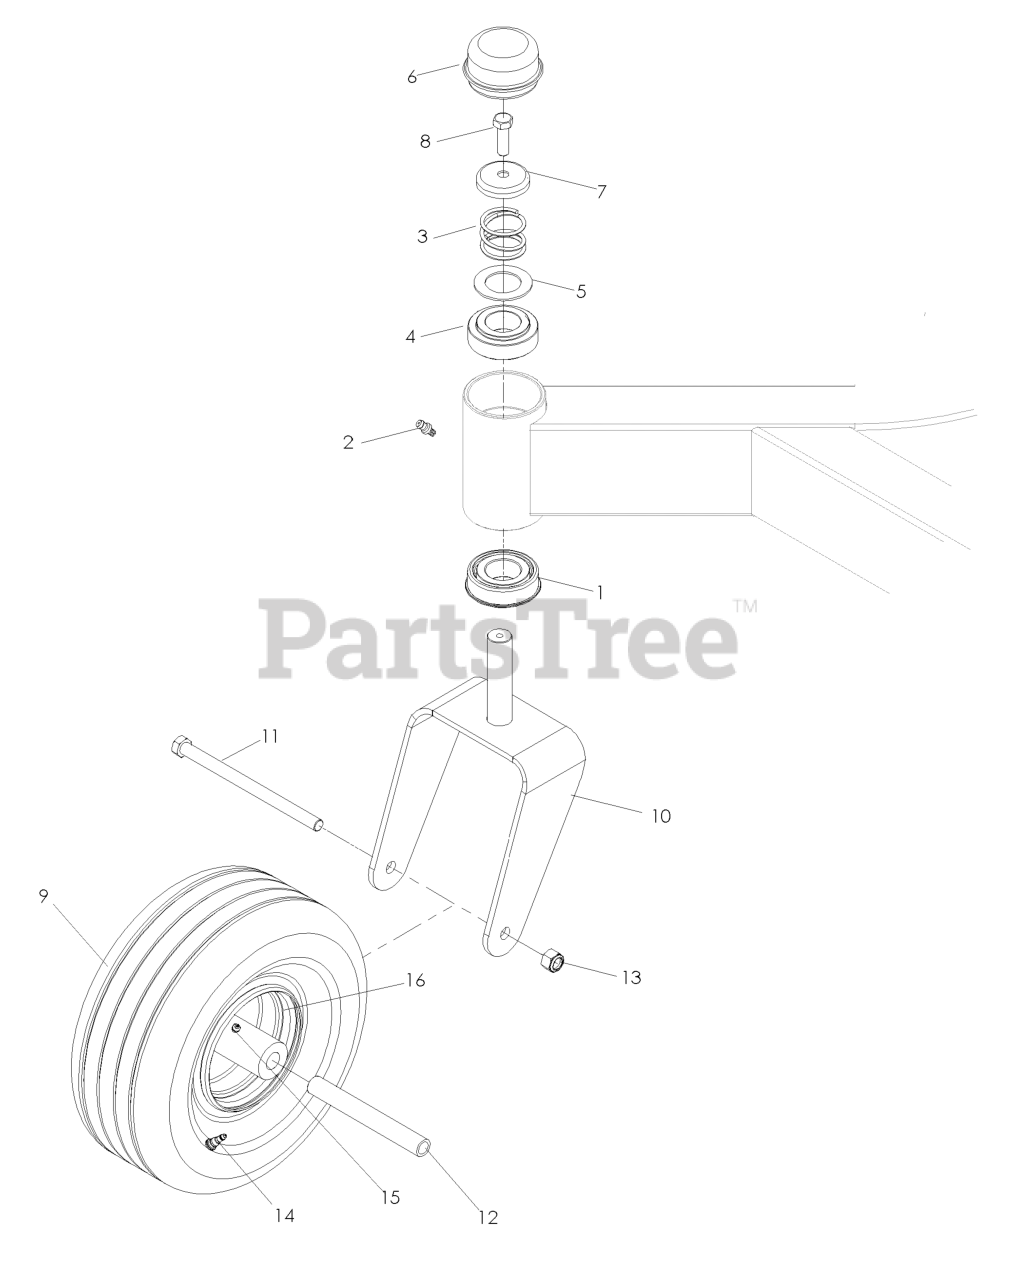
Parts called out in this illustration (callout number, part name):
1	BEARING FLANGED
2	ZERK, 3/16, DRIVE IN
3	SPRING, CASTER
4	BUSHING, CASTER
5	WASHER, 1.025 ID X 1.64
6	GREASE CAP
7	CASTER.PLUG
8	HCS 5/16C X 1
9	TIRE.ASSEM.13X5-6.SMOOTH.SILVE
10	YOKE, CASTER
11	SCREW 1/2C X 7 1/2 HEX CAP
12	SPACER, CASTER
13	NUT 1/2-13 HEX NYLOC ZD
14	VALVE STEM TR-412
15	ZERK 1/8 NPT
16	RIM
